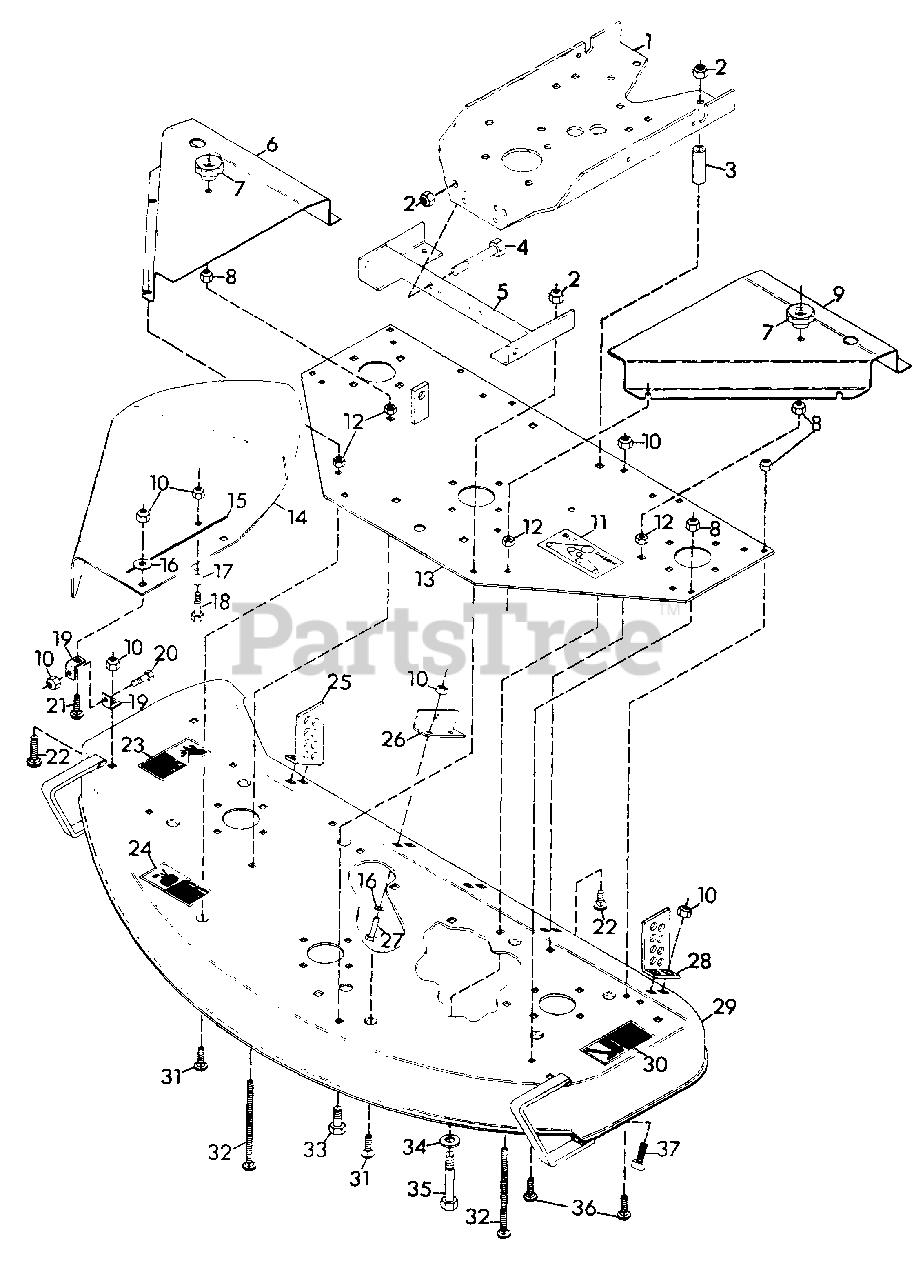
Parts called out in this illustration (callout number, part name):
1	SUPPORT, GEAR HOUSING
2	NUT, LOCK 1/2-13
3	SPACER, .510X.840X2.43
4	BOLT, HEX 1/2-13X1.375
5	BRACKET, HEIGHT ADJUSTMENT
6	COVER, PULLEY R.H.
7	KNOB
8	NUT, LOCK 5/16-18
9	COVER, PULLEY L.H.
10	NUT, LOCK 3/8-16
11	DECAL, BELT INSTALLATION
12	NUT, JAM 5/16-18
13	WELDMENT, SUPPORT PLATE
14	SHIELD, SAFETY EXTENSION 50" MOWER
15	STRIPE
16	WASHER, FLAT .406X.812X.065
17	STOP, CHUTE
18	BOLT, HEX 3/8-16X1.50
19	TAB, SPRING
20	BOLT, HEX 3/8-16X.875
21	BOLT, 3/8-16X1.00 RD HD SQ NK
22	BOLT, 3/8-16X.75 RD HD SQ NK
23	DECAL, DANGER HAND
24	DECAL, WARNING EYE
25	PLATE, REAR ADJUSTMENT
26	BRACKET, LIFT
27	BOLT, HEX 3/8-16X1.00
28	PLATE, REAR ADJUSTMENT
29	WELDMENT, 50 INCH DECK
30	DECAL, DANGER FOOT
31	BOLT, CARRIAGE 5/16-18X1.00
32	BOLT, HEX 5/16-18X3.50
33	BOLT, HEX 1/2-13X1.25
34	WASHER, FLAT .531X1.062X.095
35	BOLT, HEX 1/2-13X3.75
36	BOLT, 5/16-18X.75 RD HD SQ NK
37	BOLT, HEX 3/8-16X1.25
NS	DECAL, PRO MASTER-50 MOWER
